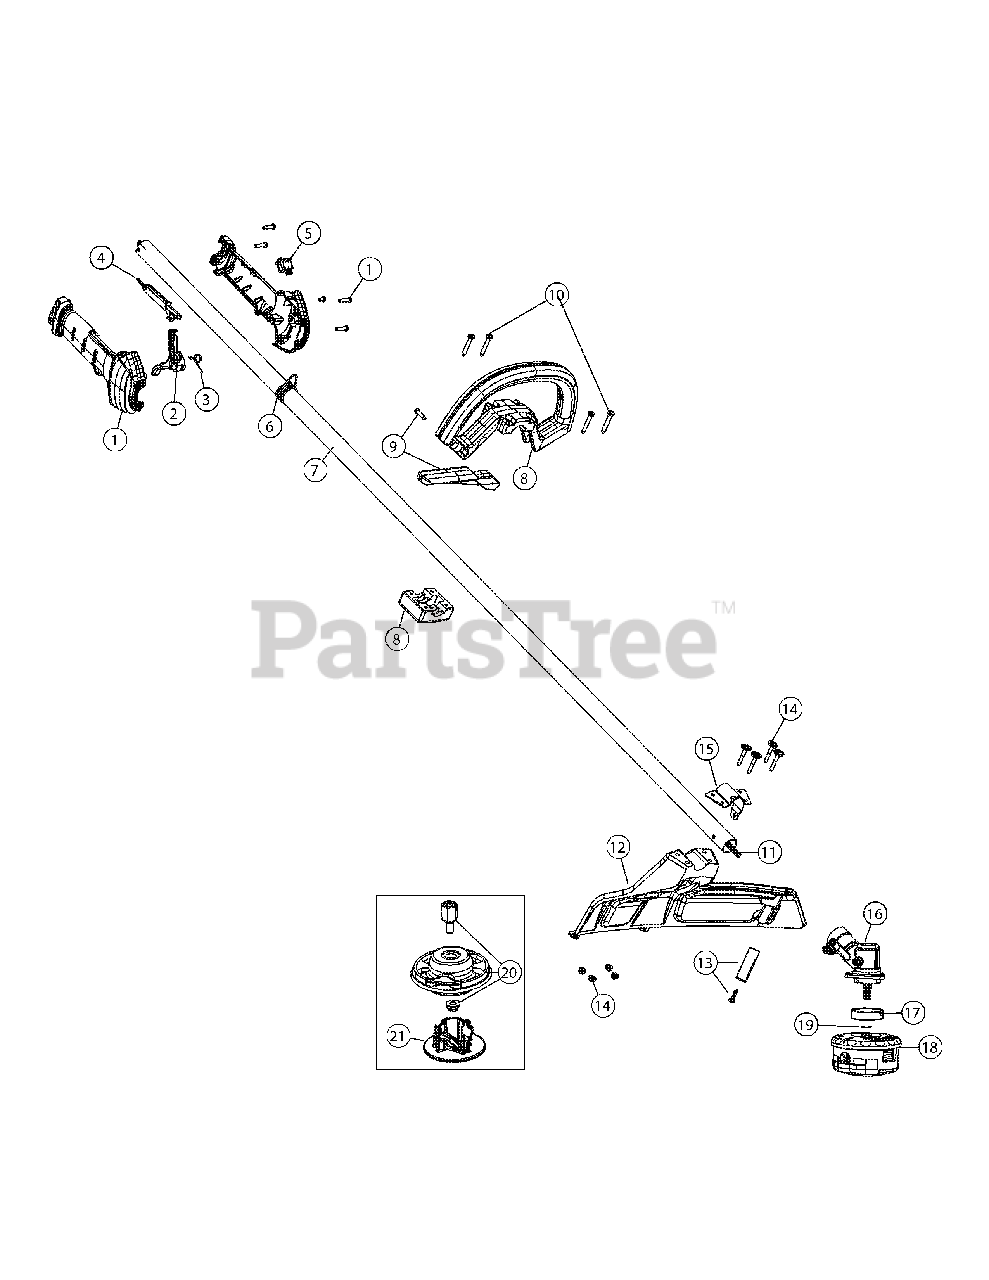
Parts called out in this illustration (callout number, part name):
1	Throttle Housing Assembly
2	Throttle Trigger
3	Spring
4	Throttle Lock-out
6	Shoulder Strap Clip
7	Shaft Housing
8	D-Handle Assembly
9	Barrier Bar Assembly
11	Flexible Drive Shaft
12	Shield Assembly
13	Blade Assembly
15	Guard Mounting Bracket
16	Gearbox
17	Gearbox Spacer
18	Cutting Head Assembly
19	Palnut
20	Fixed Line Head
21	Glide Plate
